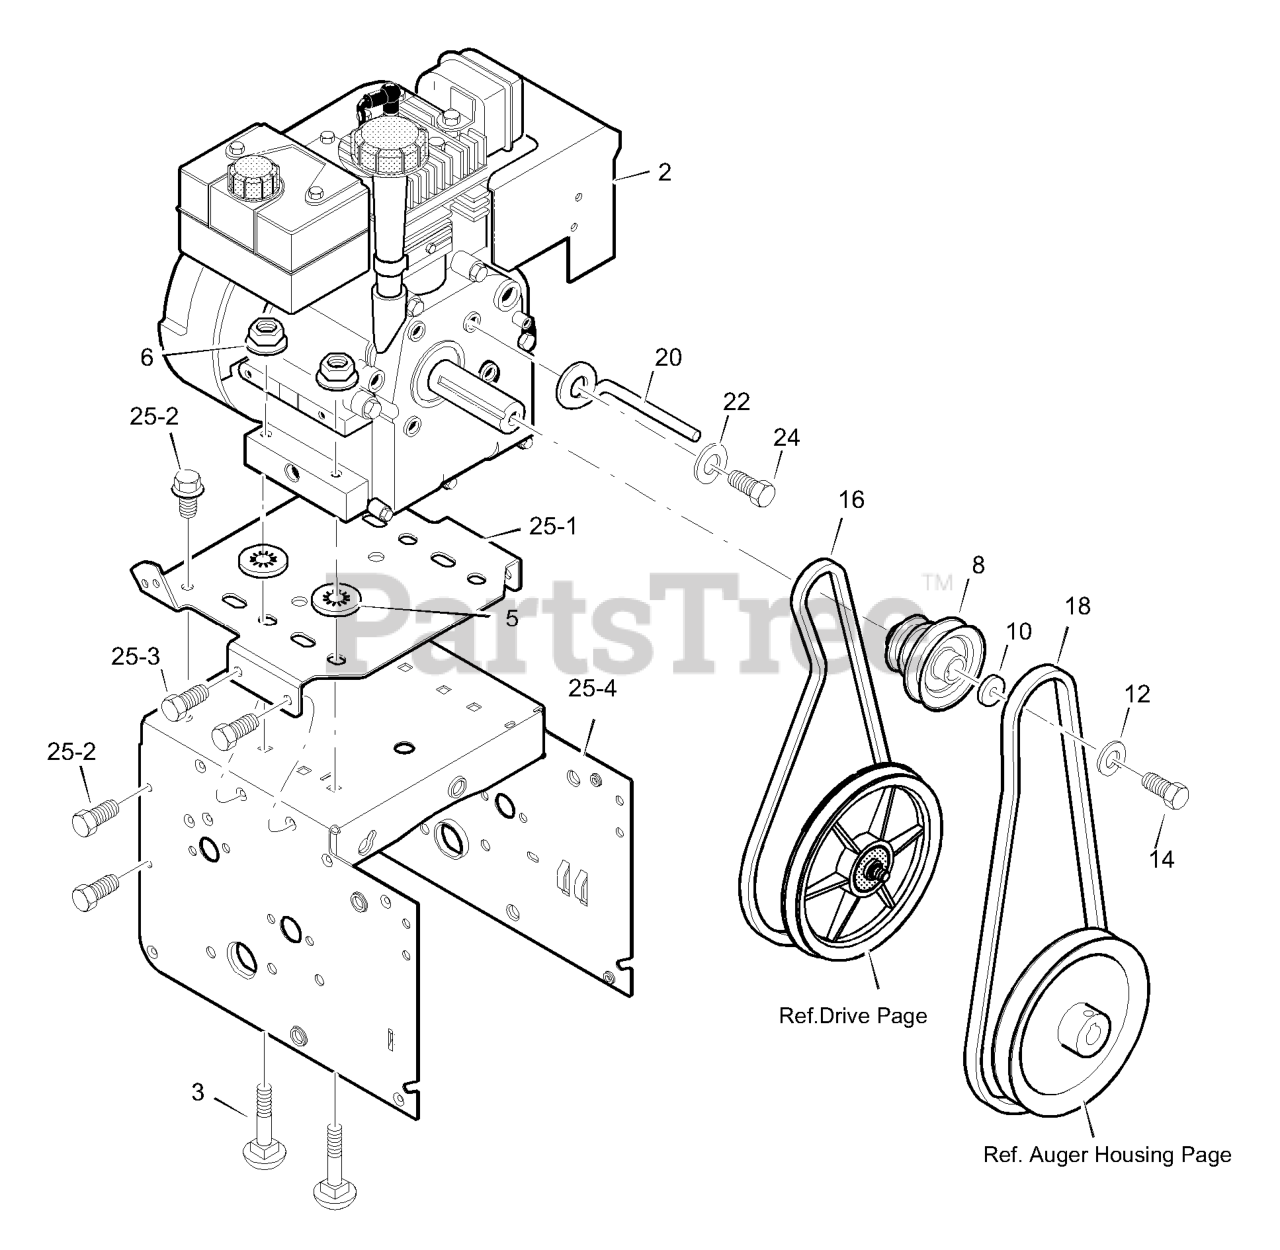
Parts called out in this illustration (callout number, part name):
2	ENGINE
3	BOLT, CARRIAGE 5/16-18
5	RETAINER, PUSH
6	NUT 5/16-18
8	PULLEY, ENGINE
10	WASHER
12	WASHER .38ID
14	SCREW, 3/8-24 x 1.00
16	BELT, V
18	BELT, V 4L
20	GUIDE, BELT
22	WASHER .31X.58X.08
24	SCREW, 5/16-24 x 0.75
25-1	PLATE, ENGINE MOUNT
25-2	SCREW, TAP 1/4-20 X .63
25-3	SCREW, TAP 5/16-18 X .50
25-4	FRAME, MOTOR BOX
